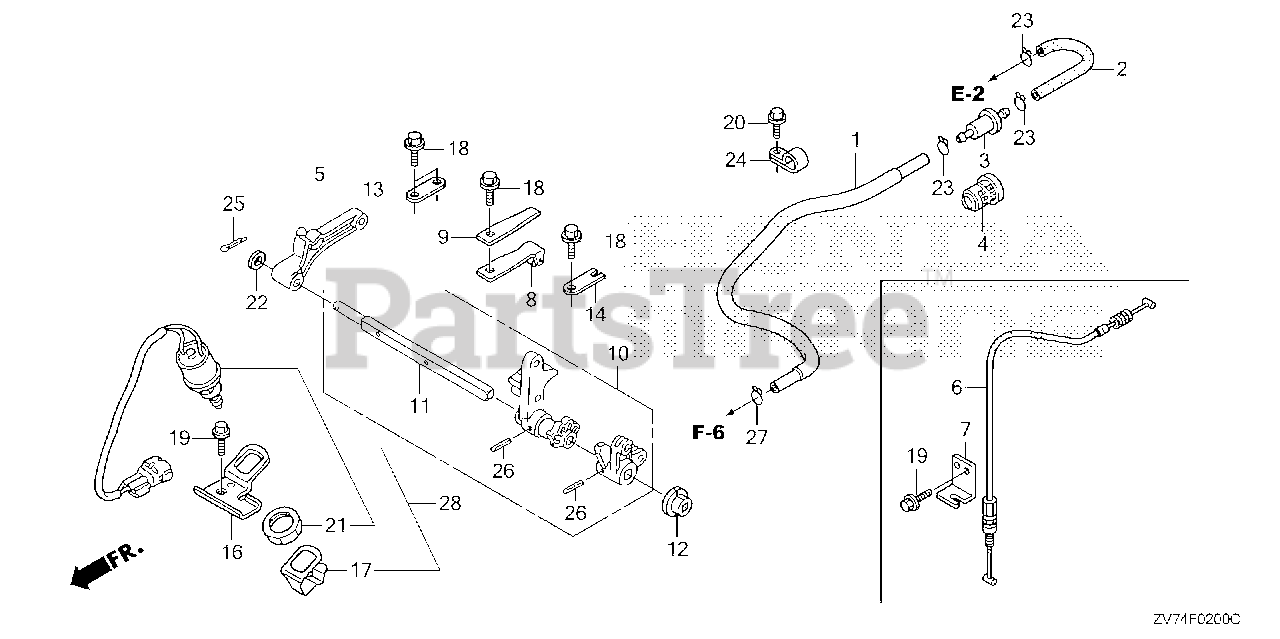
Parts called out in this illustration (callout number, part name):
1	TUBE, FUEL
1	TUBE, FUEL (FKM)
2	TUBE B, FUEL
2	TUBE B, FUEL (FKM)
3	FILTER, FUEL
4	SUSPENSION, STRAINER
5	ARM, THROTTLE
8	SPRING, CLICK
9	SPRING, CLICK ASSIST
10	SHAFT, SHIFT
11	SHAFT, SHIFT
12	BUSH, SHAFT
13	PLATE, SHIFT
14	PLATE, SHIFT SHAFT
15	SWITCH ASSY., NEUTRAL
16	BRACKET, NEUTRAL SWITCH
17	PLATE, NEUTRAL SWITCH
18	BOLT, FLANGE (6X12) (CT200)
19	BOLT, FLANGE (6X12) (CT200)
20	BOLT, FLANGE (5X10) (CT200)
21	NUT, HEX. (20MM)
22	WASHER (7.5MM)
23	CLIP, TUBE (B10)
23	CLIP, TUBE
24	CLIP (14MM)
25	PIN, SPLIT (2.0)
26	PIN, SPRING (3X20)
27	CLIP, TUBE (B12)
28	SWITCH SET, NEUTRAL
